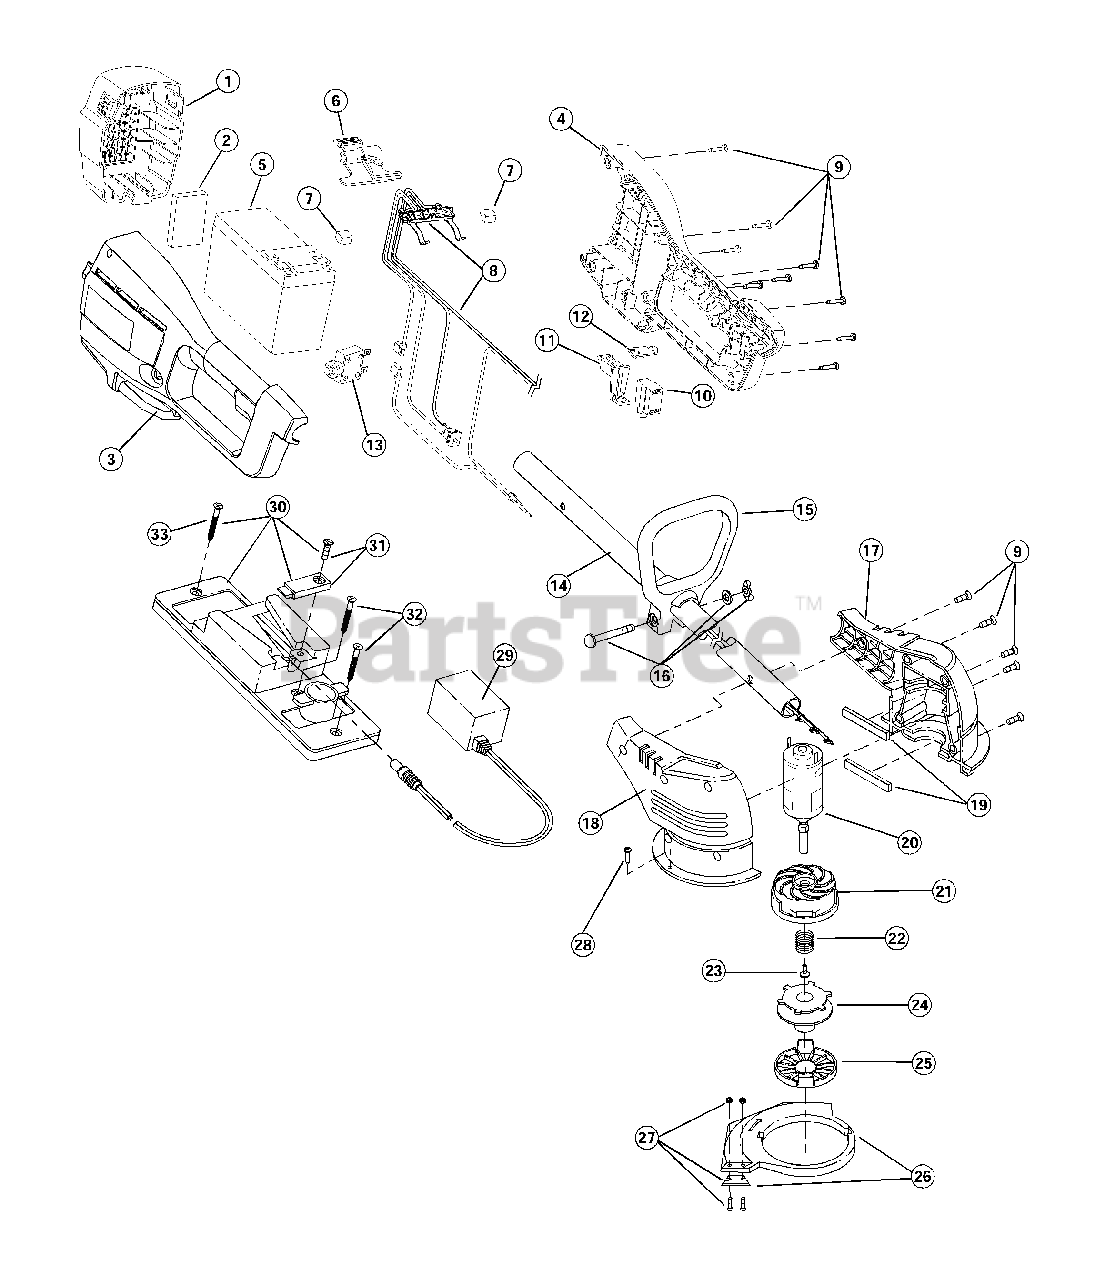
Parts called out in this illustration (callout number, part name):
1	Battery Door
2	Foam Pad
3	Right Battery Housing
4	Left Battery Housing
5	12 Volt Battery
6	Battery Latch
7	Terminal Spacer
8	Wiring Harness Assembly
9	Housing Screw
10	Switch Assembly
11	Trigger
12	Lock-Off Button
13	Circuit Breaker
14	Motor Wire Tube
15	D-Handle
16	Handle Hardware
17	Left Motor Housing
18	Right Motor Housing
20	Motor with Shaft
21	Outer Spool and Eyelet/Motor Fan
24	Inner Reel with .080" Line
25	Reel Cover
26	Guard and Blade Assembly
27	Blade Assembly
28	Guard Screw
29	12 Volt Charger
30	Charging Station Stand
31	Barrel Clamp with Screw
32	Mounting Screw
